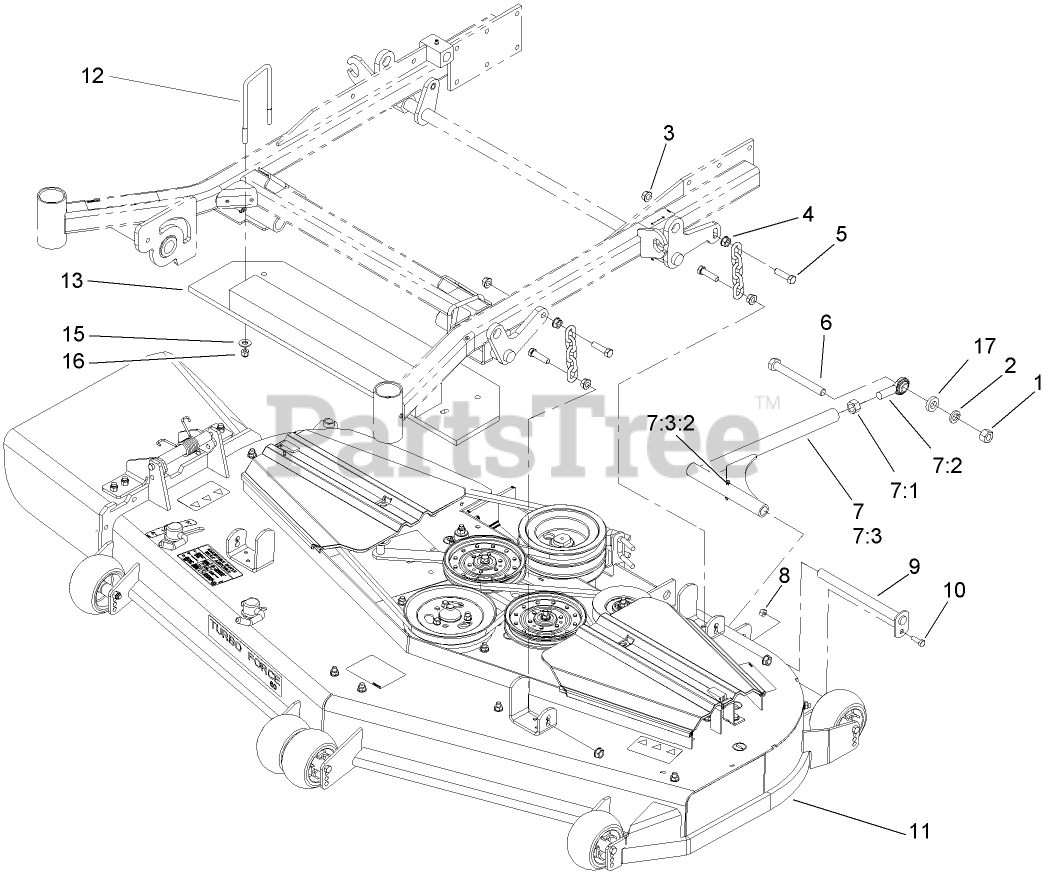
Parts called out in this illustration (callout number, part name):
1	WASHER-LOCK
2	NUT-HEX
3	NUT-HF
4	CHAIN-LIFT, DECK
5	SCREW-HH
6	SCREW-HH
7	STRUT ASM
7:1	BALLJOINT-SPHERICAL
7:2	NUT-HEX
7:3	STRUT-DECK
7:3:2	FITTING-GREASE
8	NUT-LOCK, NI
9	PIN-STRUT
10	SCREW-HH
11	Deck ASM
12	U-BOLT, 3IN
15	WASHER-FLAT
16	NUT-LOCK, NI
17	SPACER
